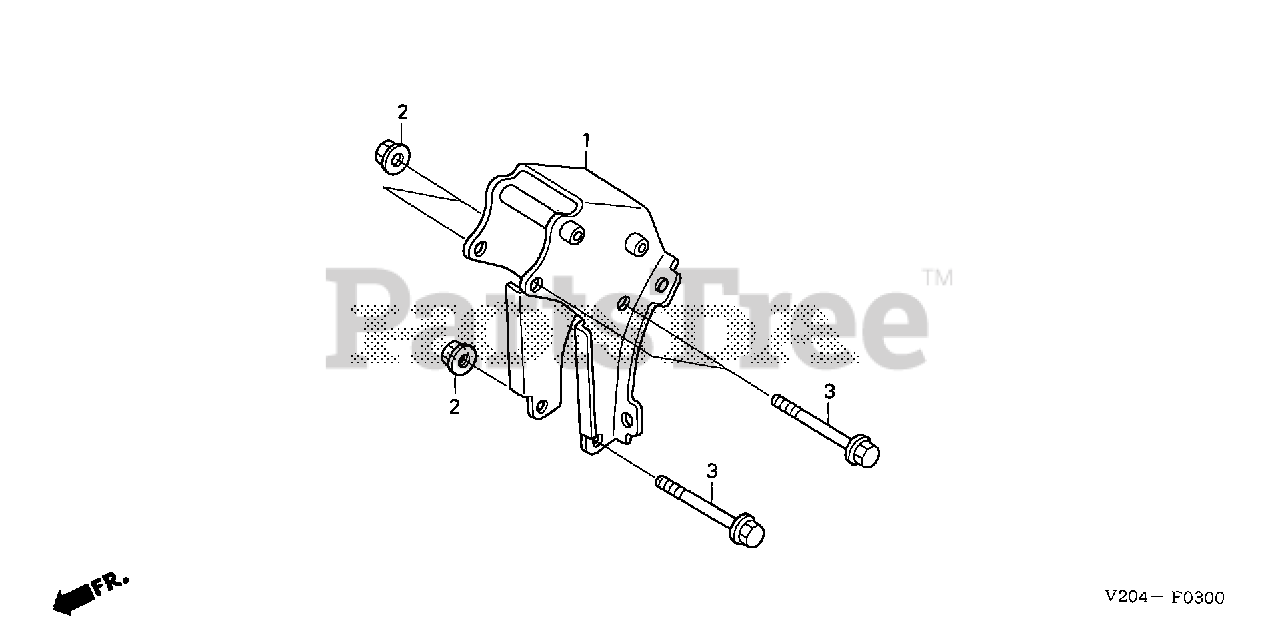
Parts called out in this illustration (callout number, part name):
1	COLUMN, HANDLE *R280* (POWER RED)
2	NUT, FLANGE (12MM)
3	BOLT, FLANGE (12X105)
